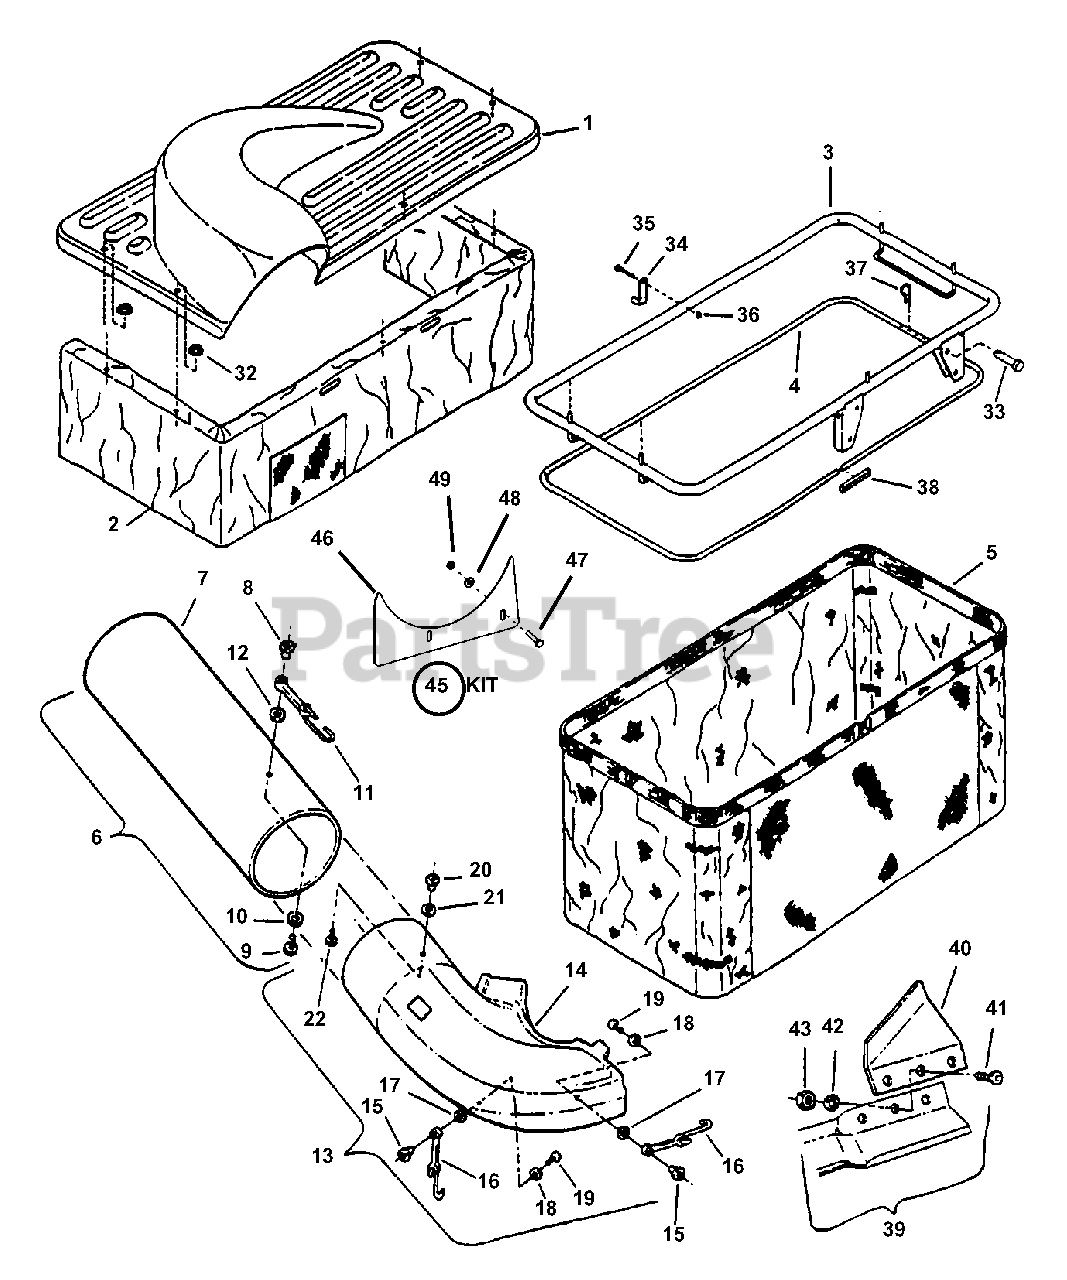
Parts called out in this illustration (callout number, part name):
1	TOP, Container
2	SKIRT, Dust
3	FRAME
4	ROD, Bag
5	BAG, Grass Catcher
6	ASSEMBLY, Tube/Strap
7	TUBE, Grass
8	NUT, #10-24 Weld
9	SCREW, #10-24 x 5/8" Pan Head
10	WASHER, 7/32" Flat
11	ASSEMBLY, Strap Mounting
12	WASHER, 3/16" Flat
13	ASSEMBLY, Adapter/Strap
14	ADAPTER
15	NUT, #10-24 Weld
16	ASSEMBLY, Strap Mounting
17	WASHER, 3/16" Flat
18	WASHER, 7/32" Flat
19	SCREW, #10-24 x 5/8" Pan Head
20	NUT, 5/16-18 "T"
21	WASHER, 11/32" Flat
22	SCREW, 5/16-18 x 5/8" Pan Head
32	WASHER, Faceted
33	PIN, 5/16 x 1-11/16" Clevis
34	LATCH, Grass Catcher
35	SCREW, #10-32 x 1-1/16" Hex Head Cap, Grade 2
36	NUT, #10-32 Hex Top Lock
37	PIN, 3/32 x 1-1/2 Hair
38	CONNECTOR, Bag Rod
39	KIT, Air Lift
40	LIFTS, Air
41	SCREW, 5/16-24 x 21/32" Machine
42	WASHER, 5/16" Internal Tooth Lock
43	NUT, 5/16-24 Hex
45	KIT, Catcher Debris Shield
46	SHIELD, Debris
47	BOLT, 1/4-20 x 1-1/2" Hex
48	WASHER, 1/4" Flat
49	NUT, 1/4-20 Hex Top Lock
